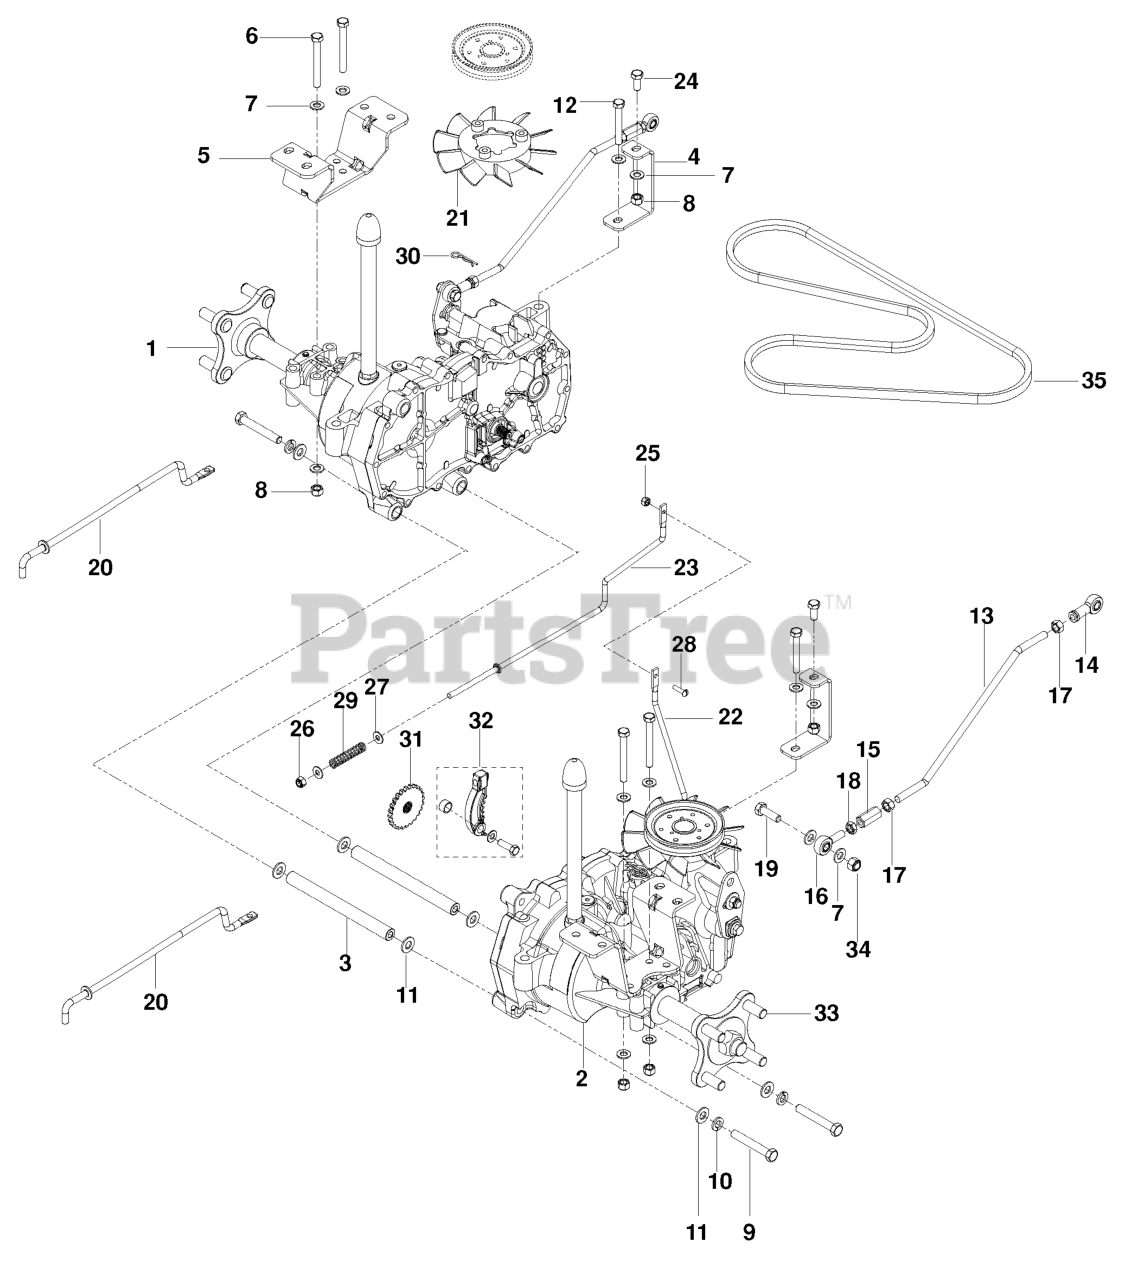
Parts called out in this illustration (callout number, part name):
1	HG_EZT, LT
2	HG_EZT, RT
3	SPACER TUBE, EZT
4	SUPPORT.FRONT.TRANS.BLACK.
5	EZT MOUNT, REAR, BLACK
6	HCS 5/16C X 2-3/4
7	FLAT WASHER 5/16 SAE
8	NUT 5/16 NYLOC
9	HCS 3/8C X 2 1/2
10	SLW 3/8 STD
11	WASHER 3/8 SAE FLAT
13	RP.ROD, MOTION CONTROL
14	RH ROD END
15	ROD END COUPLER
16	RP.ROD.END.LH
18	NUT 5/16F LEFTHAND
19	HCS 5/16C X 1
20	LINKAGE, BYPASS, EZT
21	HG_HYDRO FAN 51365
22	LINKAGE.BRAKE.LT
23	LINKAGE, BRAKE RT
24	HCS 5/16C X 3/4
25	NUT 10-24 NYLOC
26	NUT.1/4-20.HEX.NYLOC.ZD
27	WASHER 1/4 SAE
28	SCR #10-24 X 3/4
30	HAIRPIN #2
31	HG_DISC COG BRAKE 51635
32	HG_KIT BRAKE ARM (EZT)
33	HUB KIT (H-G #70314)
34	5/16-18 THIN PROF NY
35	BELT, HYDRO PUMP
